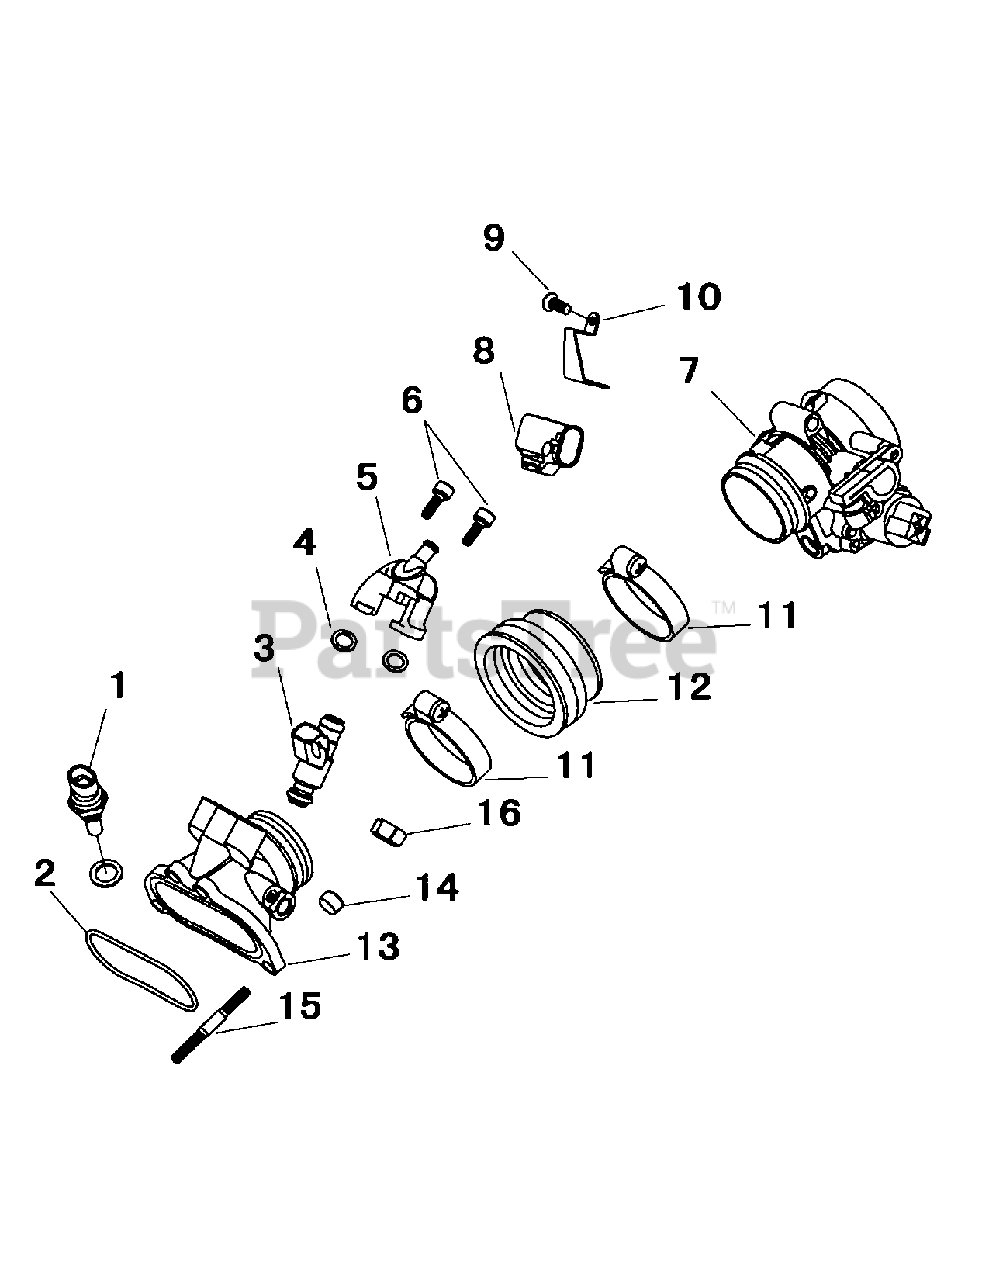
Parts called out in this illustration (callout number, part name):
1	Sensor-Water Temperature
3	Fuel Injector-25377439
5	Seat-Fuel Injection
6	Screw-Cylinder M6
7	Throttle Asm-D46-3
8	Intake air Temperature/Pressure Sensor 28086011
10	Press Plate-TMAP
12	Joint Inlet Pipe
13	Inlet Pipe
14	Bush-Inlet Pipe
15	Stud Bolt M6X32
